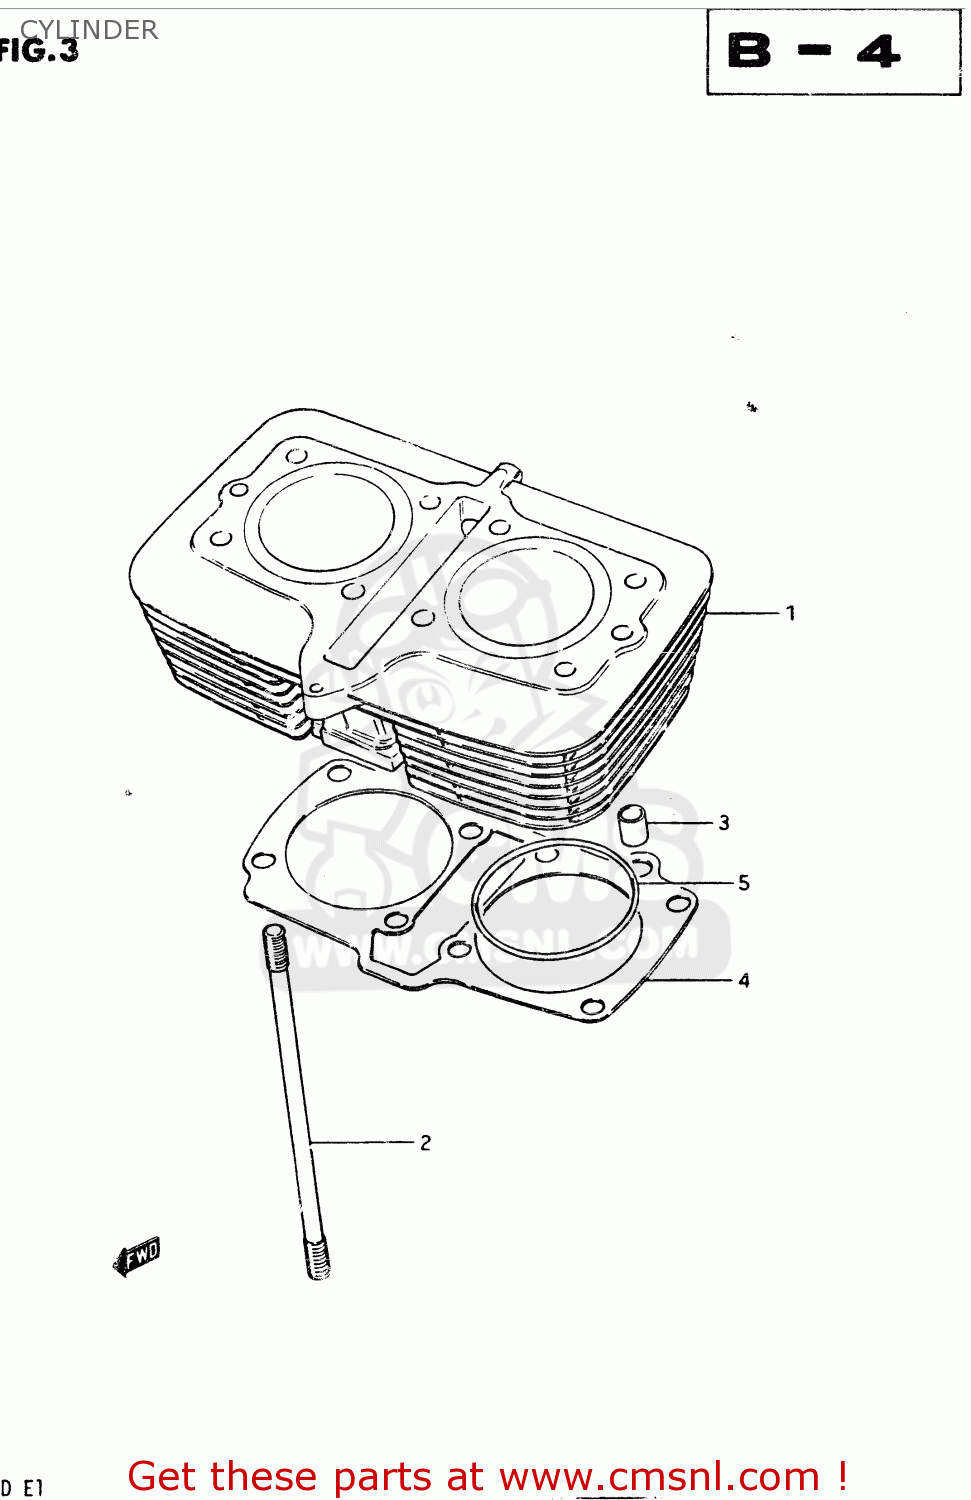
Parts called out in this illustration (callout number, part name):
1	CYLINDER
2	STUD
3	PIN
4	GASKET (T:1.2) (MCA)
5	O RING(D:2,ID:70)
